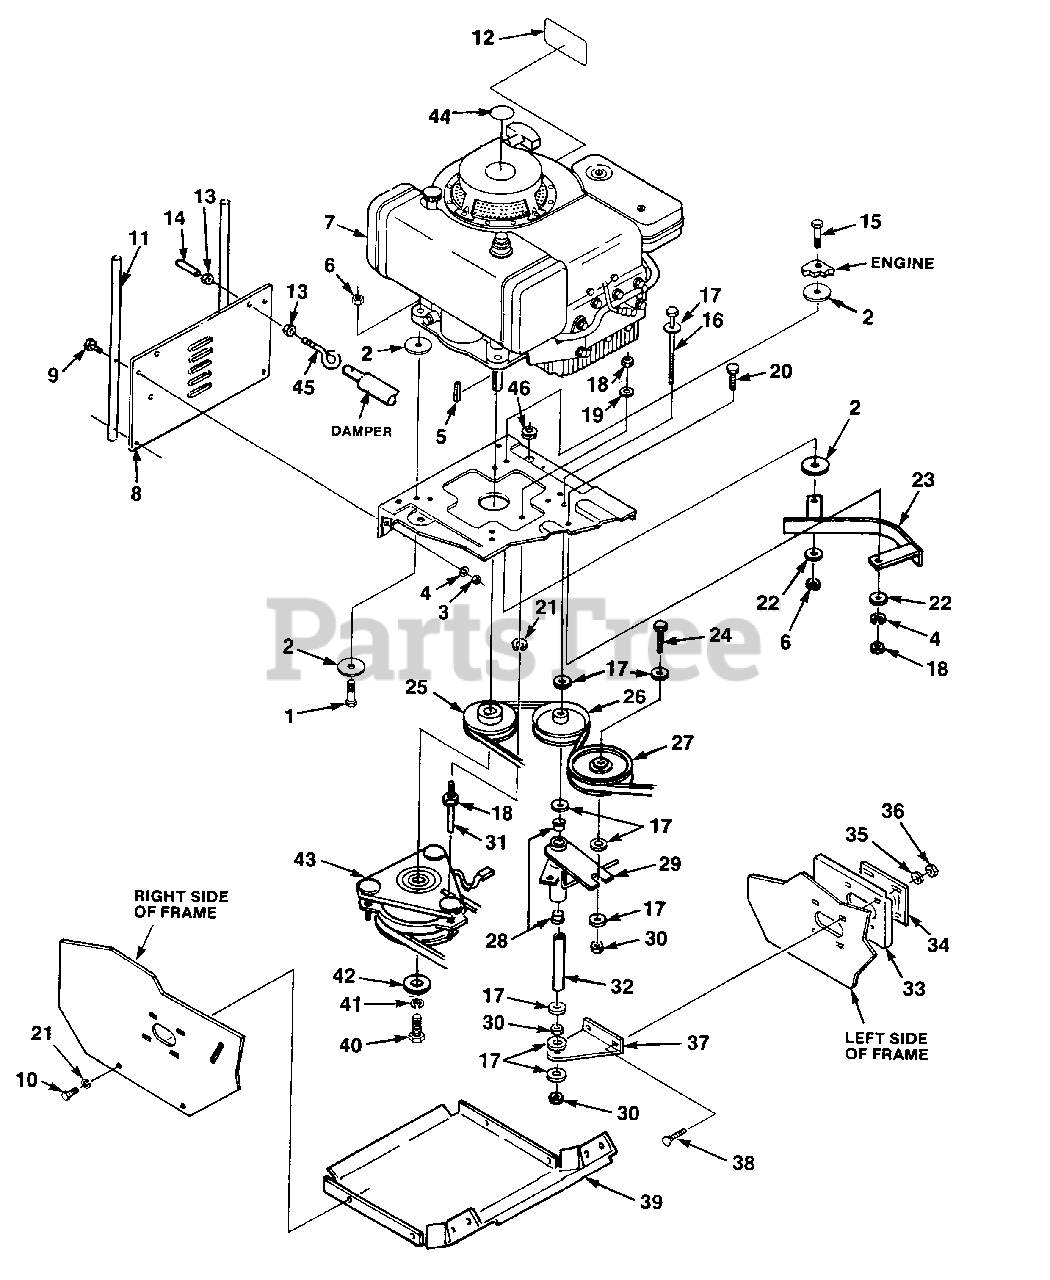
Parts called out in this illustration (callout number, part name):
1	SCREW- 5/16-18 x 1 1/2
2	WASHER -5/16
3	NUT- 1/4-20 hex
4	WASHER- 1/4
5	KEY- 1/4 x 1/4 x 1
6	NUT- Lock 5/16 x 18
7	ENGINE-
8	PANEL- Rear
9	BOLT- 5/16-18 x 3/4
10	SCREW- 1/4-20 x 5/8
11	TUBE- Catcher support
12	DECAL- (Hot Muffler)
13	NUT- (Lead 1/4-20)
15	BOLT- 5/16-18 x 1 3/4
16	BOLT- 3/8-16 x 5 1/2
17	WASHER- 3/8 flat
18	NUT- Hex 1/4-20
19	WASHER- Flat 5/16
20	BOLT- 1/4-20 x .750
21	WASHER- Lock 5/16
22	WASHER- Flat 1/4
23	GUIDE- Belt
24	BOLT- 3/8-16 x 1 3/4
25	PULLEY- Engine
26	PULLEY- Idler
27	PULLEY- Idler
28	BEARING- Flange
29	ARM- Pivot
30	NUT- Hex Centerlock 3/8-16
31	PIN- Clutch torque
33	SUPPORT- Frame
34	RETAINER & BEARING
35	WASHER- (Lock 1/4 hvy.)
36	NUT- Centerlock hex 1/4-20
38	BOLT- Rd hd carr 1/4-20 x 750
39	PAN- Bottom
40	BOLT- Hex hd 7/16-20 x 2 3/4
41	WASHER- Lock 7/16
42	CLUTCH RETAINER
43	CLUTCH- Warner
44	DECAL- 8 HP
45	BOLT- Eye
